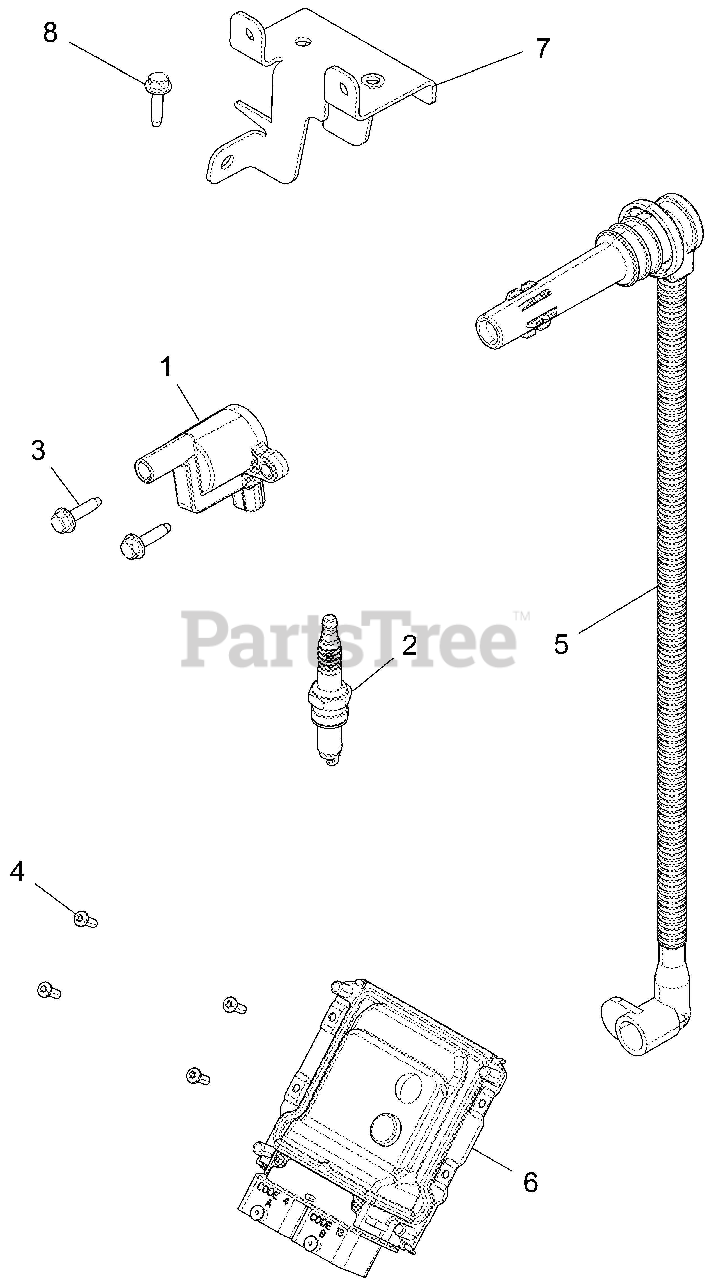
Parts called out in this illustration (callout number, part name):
1	COIL-IGNITION,500EFI
2	SPARK PLUG-10 MM
3	SCR-TX TRUSS-#14X3/4,HI/LO ZBK
4	SCR-#10X1/2-HI/LO-PN-T25,TRX-M
5	WIRE-SPARKPLUG,PTO
6	ECM-NO START,ME17
7	BRKT-AIRBOX MOUNT
8	SCR-M6X1.0X20,HXHD,FLG,TDFM,BL
